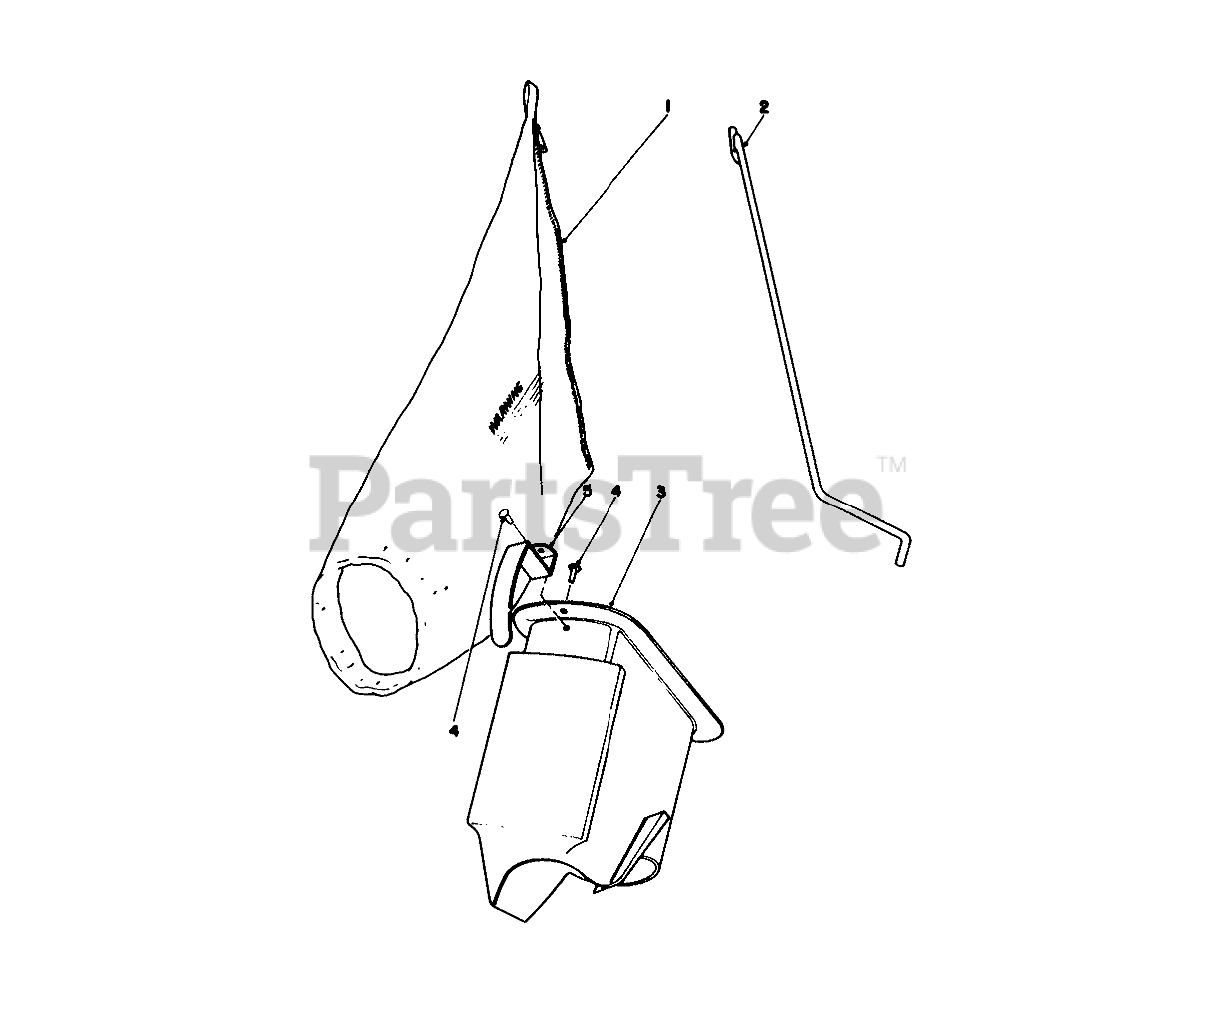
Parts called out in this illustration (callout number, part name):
1	BAG REPLACMNT44-0540
2	Bag Rod
3	Grass Chute (Incl. Ref. #4 & 5)
4	RIVET 3/16 X 7/16
5	HANDLE-GRASS CHUTE
